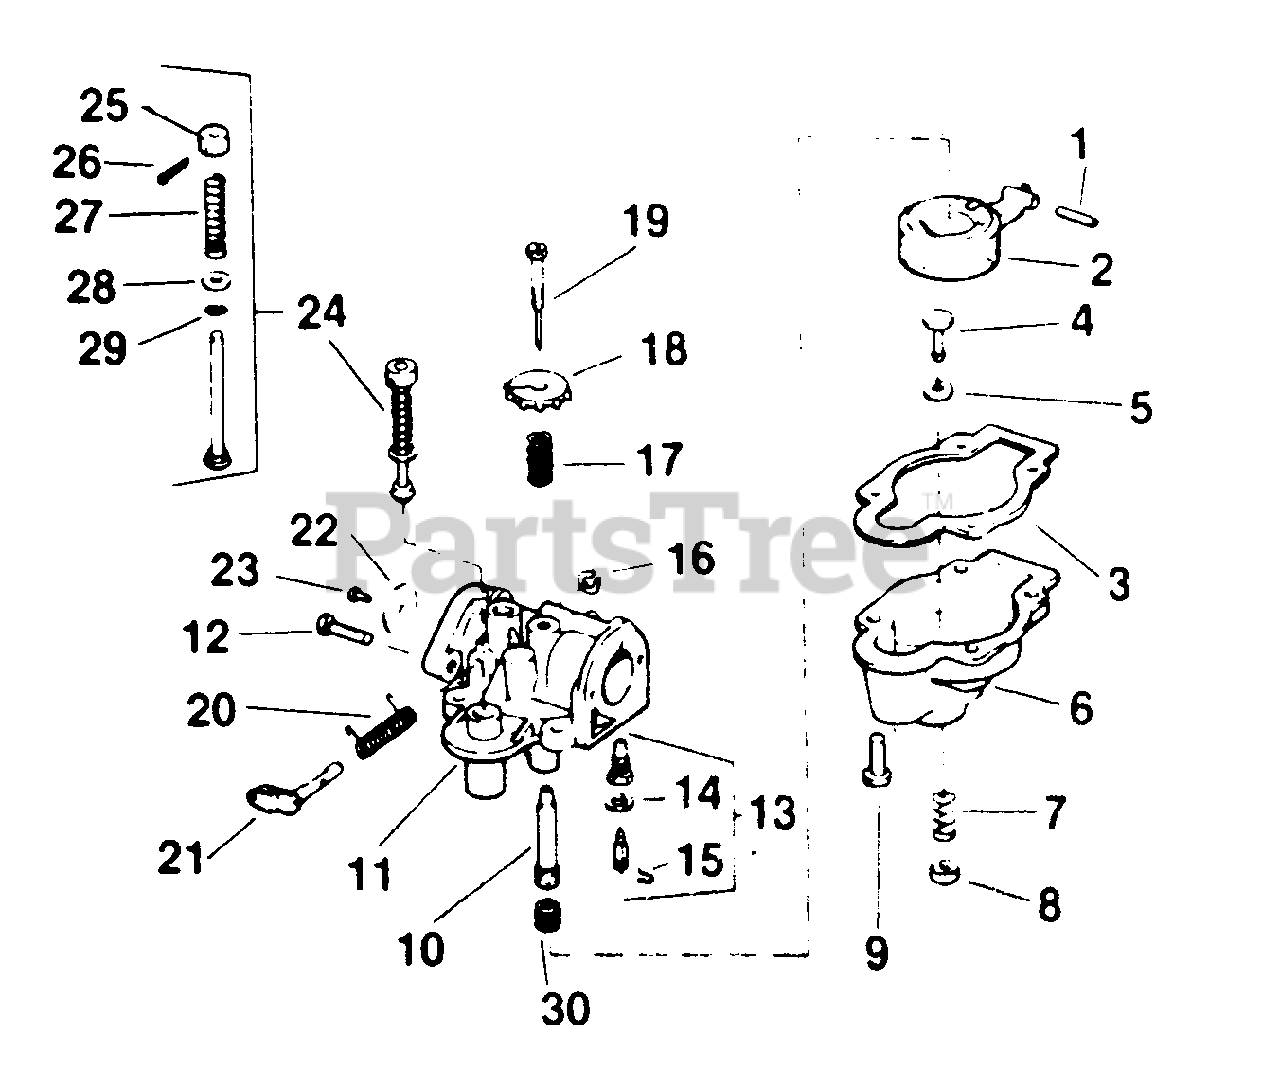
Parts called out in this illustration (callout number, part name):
1	Pin-Float Arm Hinge
2	Float and Arm Assy.
3	Gasket-Float Chamber
4	Valve Stem
5	Valve Seat
6	Chamber-Float
7	Valve Spring
8	Valve Keeper
9	Screw-Float Chamber
10	Nozzle
11	Carburetor Body Assy.
13	Float Valve & Seat
14	Washer-Float Valve Seat
15	Clip
16	Grip Ring
17	Spring-Needle Adj.
18	Knob-Needle Adj.
19	Needle Assy.
20	Spring-Throttle
21	Throttle Shaft & Lever Assy.
22	Disc-Throttle
23	Screw-Throttle Shaft Disc
24	Primer Assy.
25	Knob Primer
26	Cotter Pin
27	Spring Compression
28	Washer-Plain
29	"O" Ring
